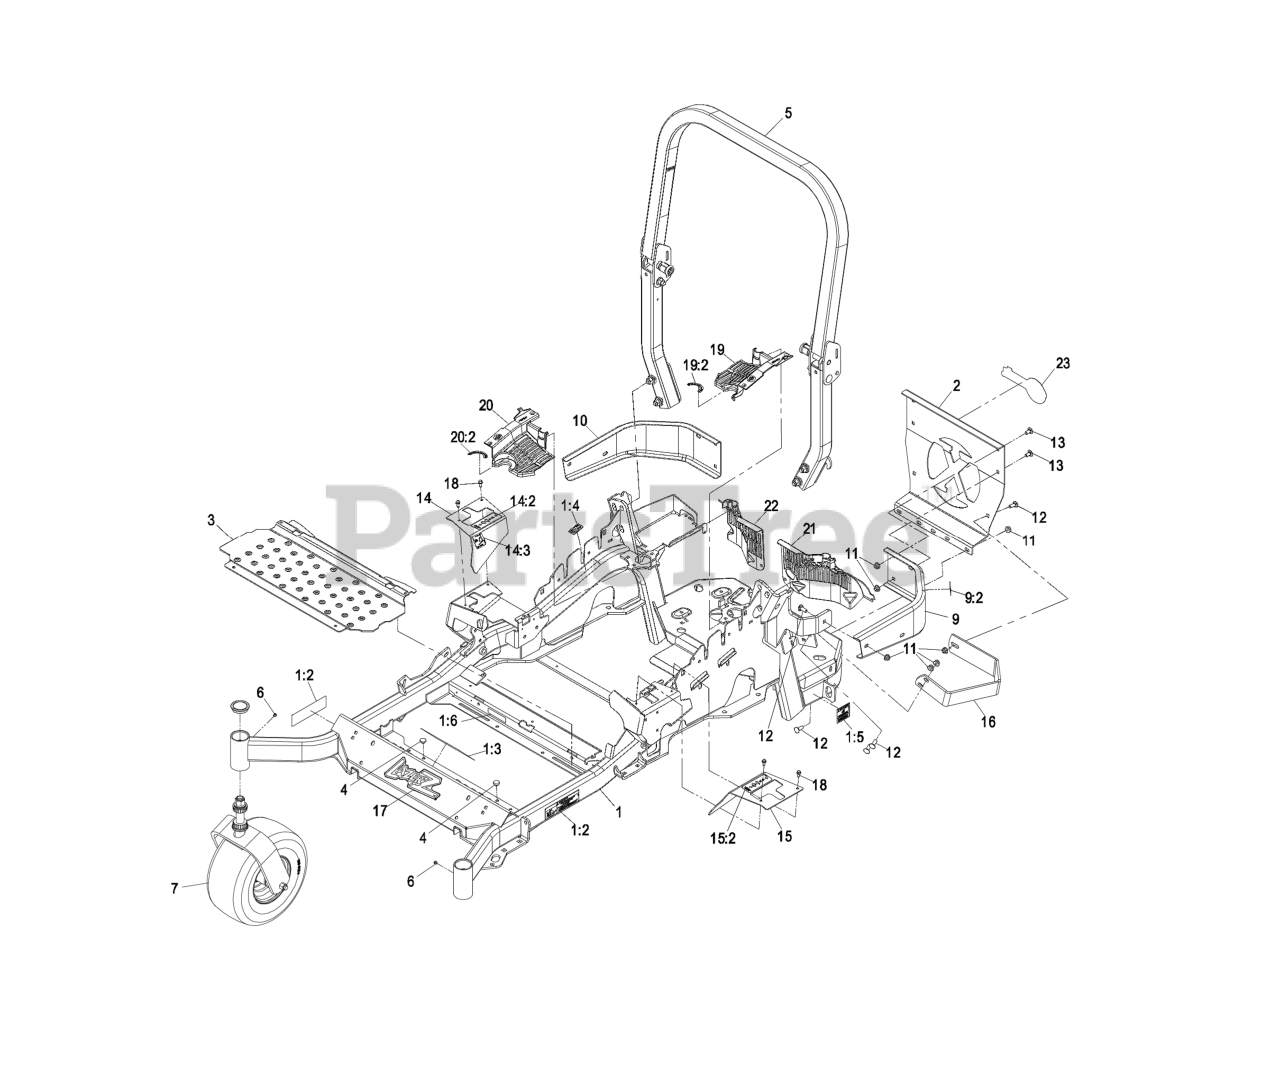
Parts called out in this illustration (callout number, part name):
1	MAIN FRAME ASM
1:2	DECAL-WARNING
1:3	DECAL-WARNING
1:4	DECAL-CAUTION
1:5	DECAL-BELT DRIVE
1:6	DECAL-ARRESTER, SPARK
2	PLATE,REAR GUARD
5	ASM,ROPS SERVICE EXMARK
9	LH BUMPER ASM
9:2	DECAL-CAUTION
10	BUMPER-RH
11	NUT-HF, NI
12	SCREW-CARR
13	SCREW-CARR
14:2	DECAL-MOTION CONTROL
15	LH MOTION CONTROL COVER ASM
15:2	DECAL-MOTION CONTROL
17	DECAL,LAZER MODEL
18	SCREW-HWH
19	LH HYDRO GUARD ASM
19:2	DECAL-HYDRO OIL
20	RH HYDRO GUARD ASM
20:2	DECAL-HYDRO OIL
21	GUARD-HYDRO REAR, LH TRIM
22	GUARD-HYDRO, REAR (RH)
